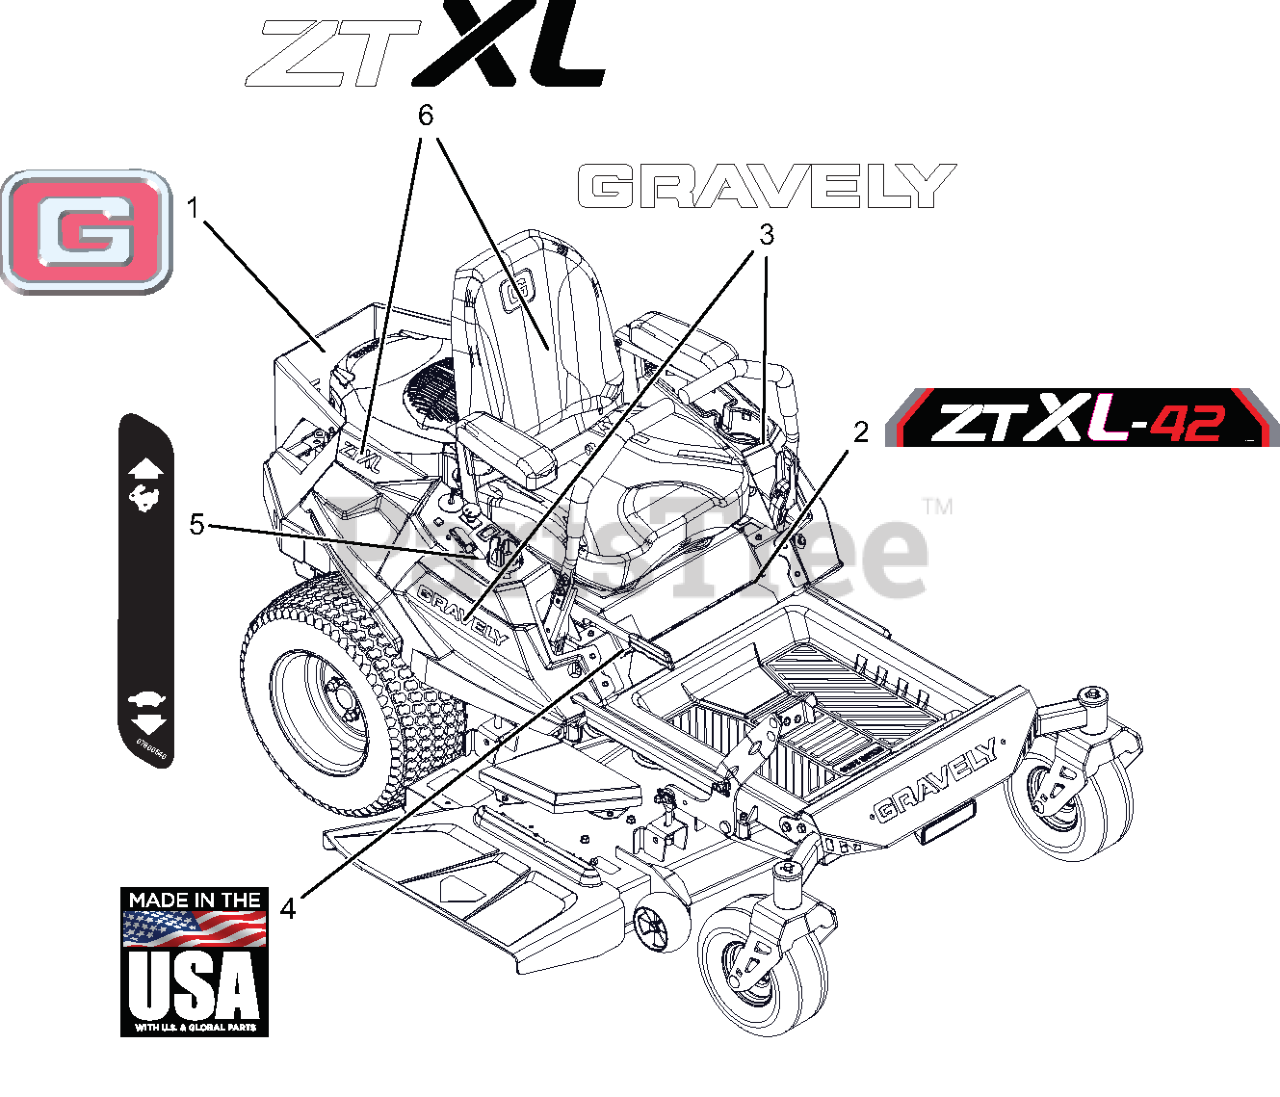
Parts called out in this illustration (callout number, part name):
1	DECAL, GRAVELY BRAND
2	DECAL, ZT XL 42"
3	DECAL, 9.5" GRAVELY LOGO
4	DECAL, MADE IN USA
5	DECAL, DASH DECAL
6	DECAL, REAR WRAP - ZTXL
